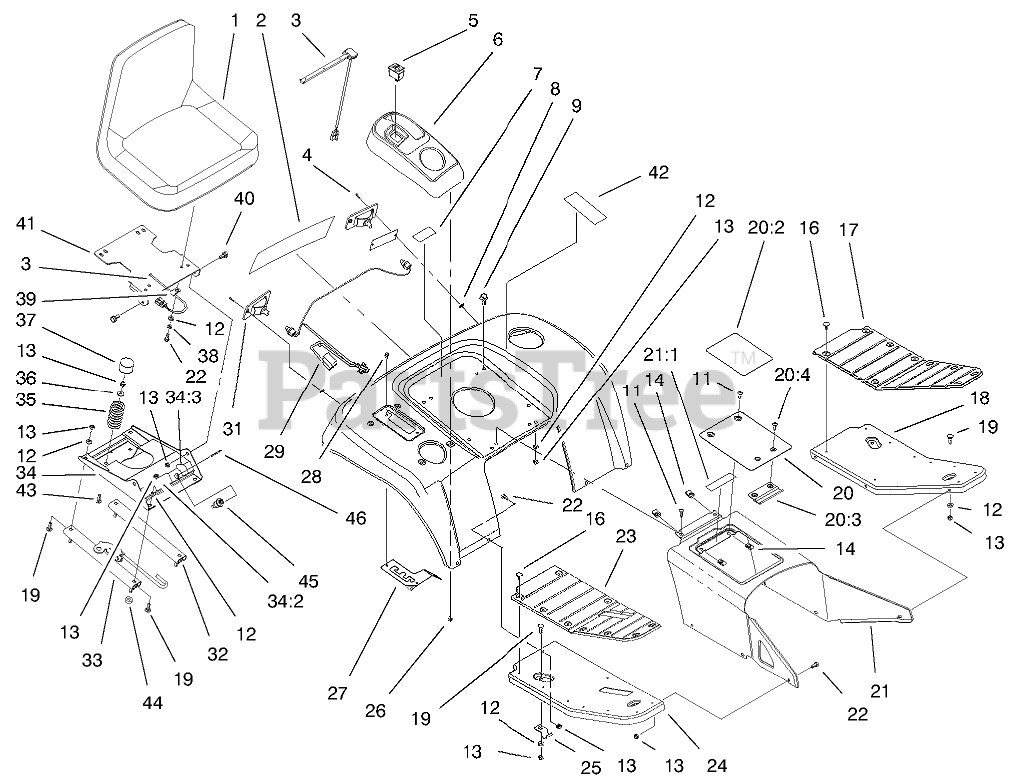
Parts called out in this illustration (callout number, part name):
1	SEAT
2	DECAL - FENDER
3	SWITCH-SEAT
4	SCREW-PPH
5	SWITCH-CRUISE
6	Pod-Control (Only On: 73552)
6	Pod-Control Int-l (Only On: 73590)
7	Decal-USA (Only On: 73552)
8	NUT-SPEED
9	SCREW-HHF
11	SCREW-HH
12	WASHER-PLAIN
13	NUT-LOCK, NI
16	FASTENER-PANEL
17	PAD-FOOTREST, LH
18	FOOTREST-LH
19	SCREW-CARR
20	ASM Cover/Decal (Only On: 73552)
20	ASM-Tunnel Cover Europe (Only On: 73590)
20:2	Decal-Danger (Only On: 73552)
20:2	Decal-Danger Europe (Only On: 73590)
20:3	RETAINER-COVER
20:4	Screw-Plastite (Only On: 73552)
20:4	Screw-Pan Hd (Only On: 73590)
21	ASM-Tunnel w/Decal (Only On: 73552)
21	ASM-Tunnel w/Decal Europe (Only On: 73590)
21:1	Decal-Danger (Only On: 73552)
21:1	Decal-Warning (Only On: 73590)
22	SCREW-HH
23	PAD-FOOTREST, RH
24	FOOTREST-RH
25	BRACKET-FOOTREST
26	SCREW-HHFTF
27	GATE-HI / LO SHIFT
28	SCREW-HWH
29	HARNESS-REAR
31	LAMP-TAILLIGHT
32	SLIDE-SLAVE, SEAT
33	SLIDE-LATCH, SEAT
34	Seat Base ASM (Only On: 73552)
34	Seat Base ASM-Intl (Only On: 73590)
34:2	Decal-Danger (Only On: 73552)
34:3	Decal-Nmir Switch (Only On: 73552)
35	SPRING-COMPRESSION
36	BUSHING
37	CAP-SPRING, SEAT
38	WASHER-LOCK
39	CLAMP-R
40	BOLT-SHOULDER
41	Mount-Seat
42	DECAL - DIESEL
43	SCREW-CARR
44	WASHER-FLAT
45	STARTER SWITCH ASM
46	KEY-IGNITION
